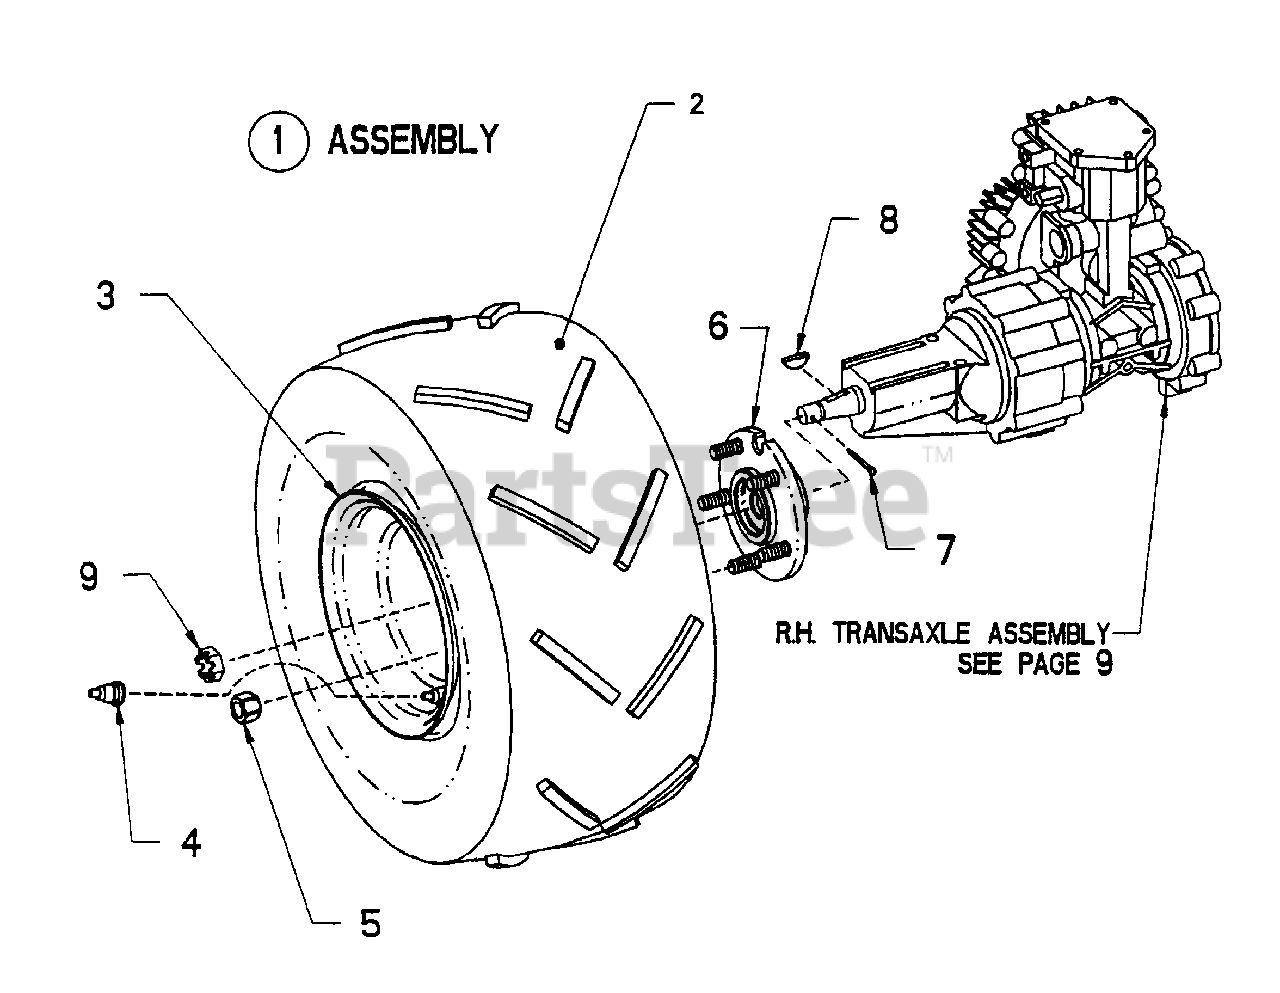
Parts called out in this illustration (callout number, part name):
2	TIRE, 21 x 11.00-8 4 ply "All Terrain"
3	RIM, 8" Dia. X 7-3/4"
4	VALVE, Air
5	NUT, 1/2-20 Lug
6	ASSEMBLY, Wheel Hub
7	PIN, Cotter, 9/64 x 1-1/2"
8	KEY, #808 Woodruff
9	NUT, 3/4-20 Slotted Hex
